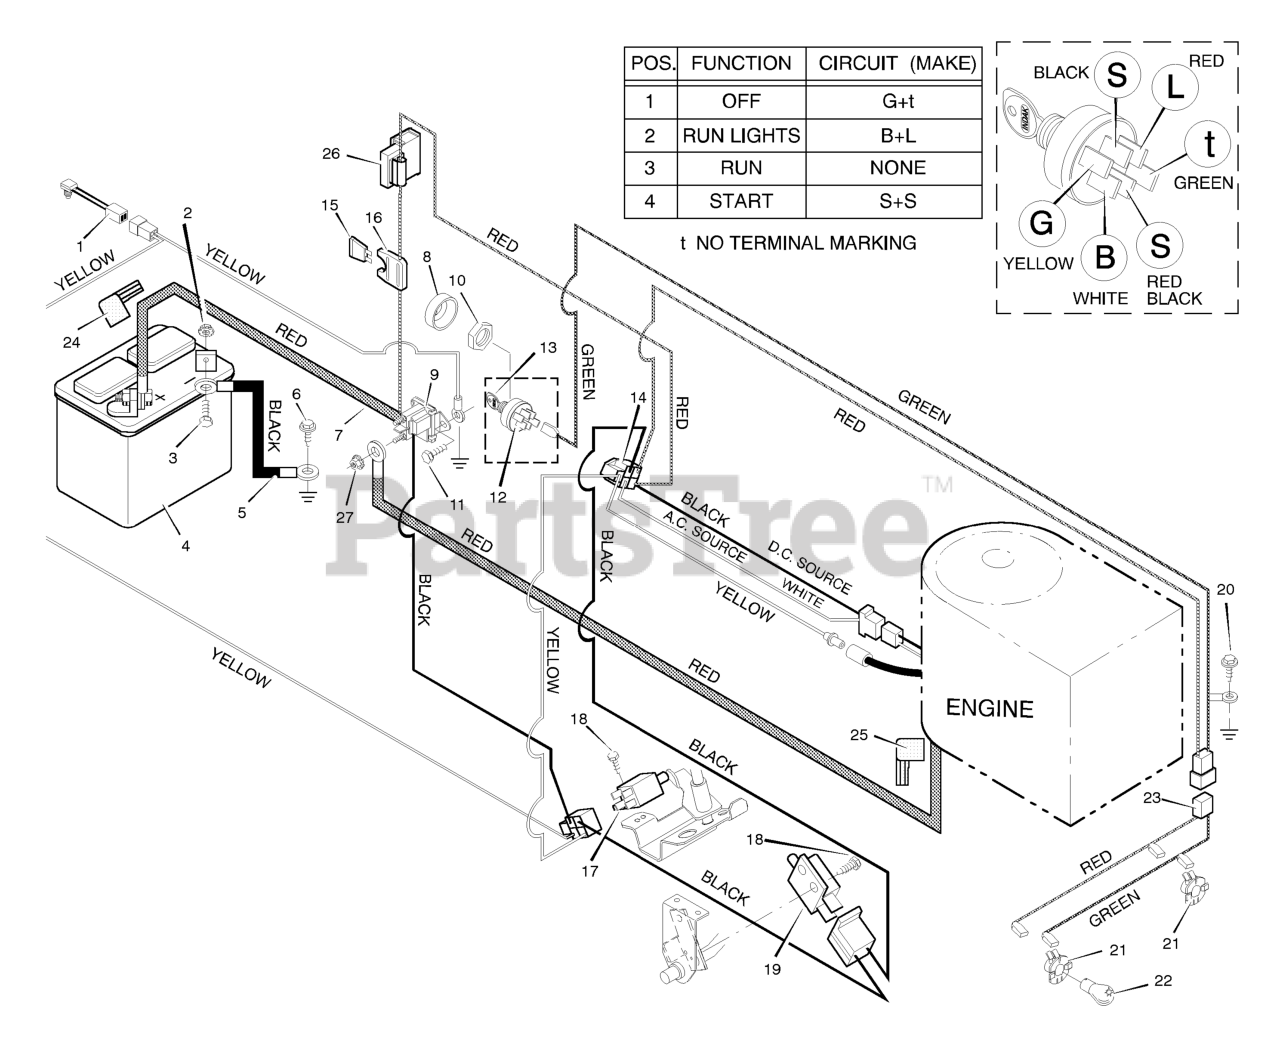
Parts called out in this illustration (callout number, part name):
1	Switch, Seat Sensor
2	Locknut
3	Bolt, Hex
4	Battery
5	Cable, Battery Ground
7	Cable, Red Battery
8	Cap, Ignition
9	Solenoid
10	Nut
12	Switch, Ignition
13	Key, Ignition
14	Harness, Chassis Wire
16	Holder, Fuse
17	Switch, Clutch
19	Switch, Clutch
20	Screw
21	Socket, Light
22	Bulb, Light
23	Harness, Light Wire
24	Cover, Terminal
25	Cover,
26	Ammeter
27	Locknut
